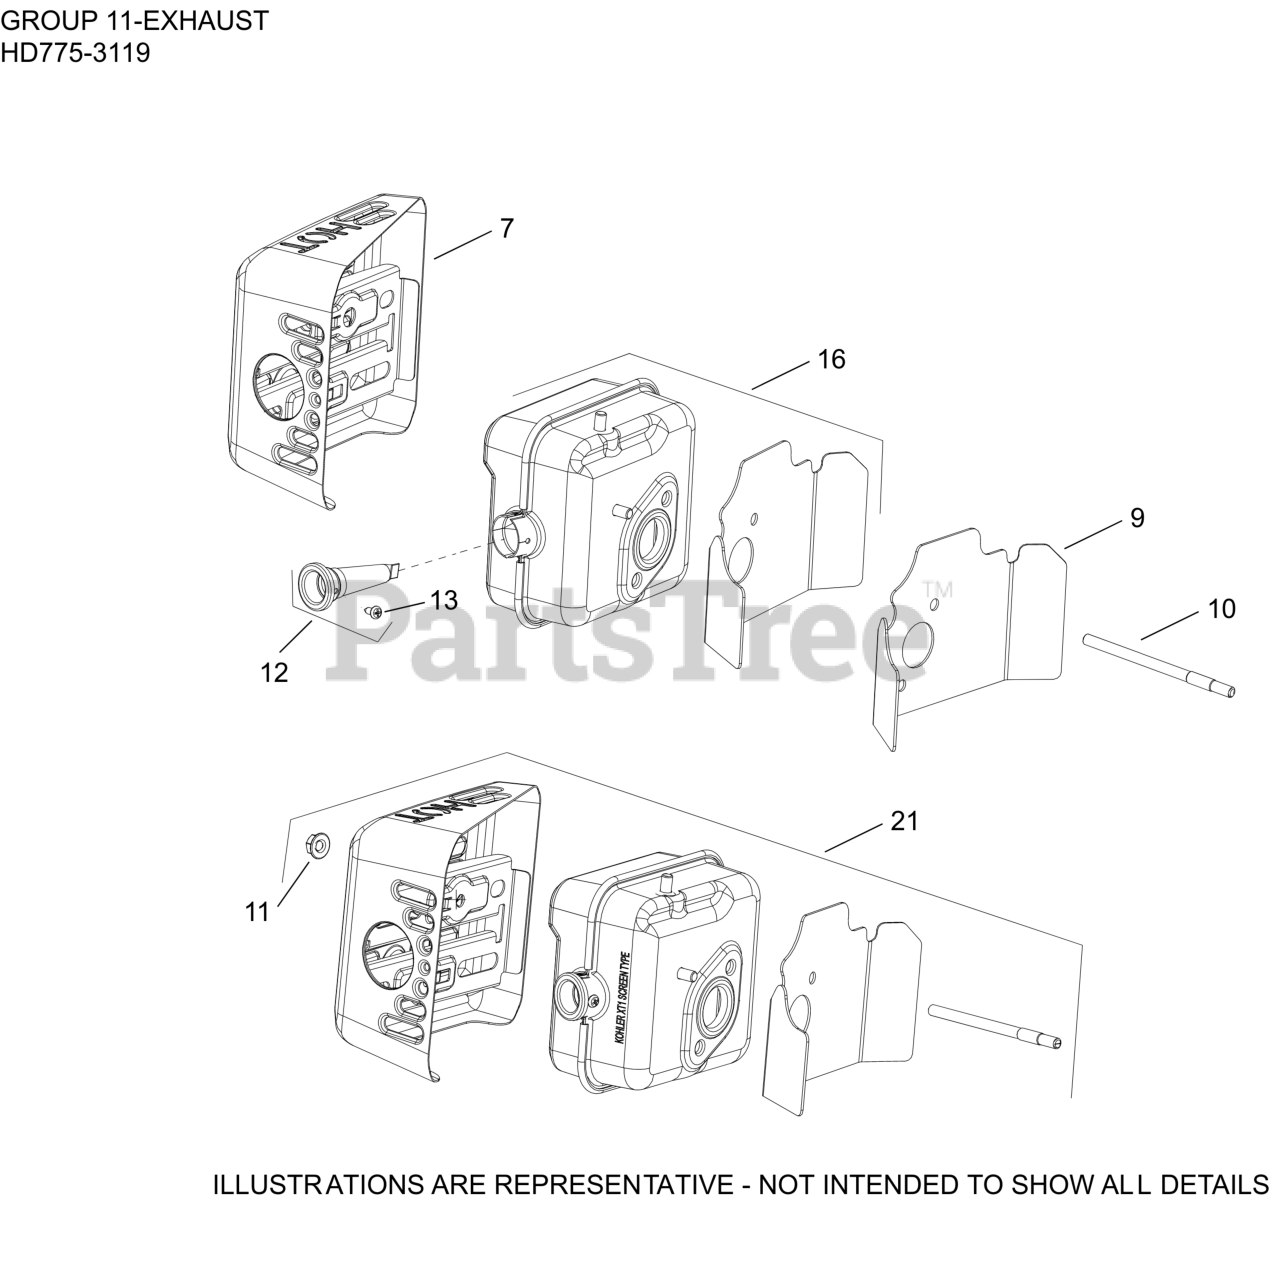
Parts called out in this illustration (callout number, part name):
7	GUARD, MUFFLER ASSEMBLY
9	GASKET, MUFFLER (HEAT DEFLECTOR)
10	STUD, EXHAUST (M6)
11	NUT, HEX FLANGE LOCK (M6)
12	KIT, SPARK ARRESTER
13	SCREW, CROSS RECESS PAN HEAD
16	KIT, MUFFLER
21	KIT, MUFFLER
